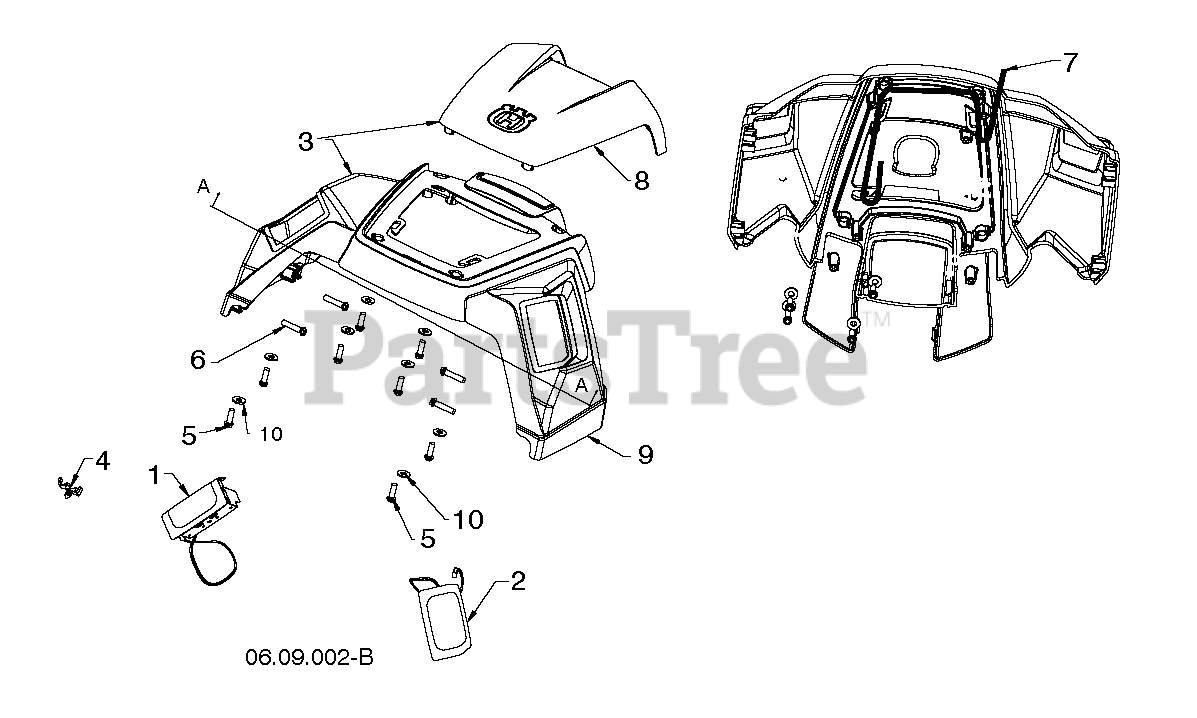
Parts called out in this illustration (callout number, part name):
1	LIGHT.LED.RH.SUBASM 12
2	LIGHT.LED.LH.SUBASM 12
3	CONTROL.SHROUD.SNOW
5	SCREW.HX.13X.750
6	SCREW.HWH.13-16X1.12
7	HARNESS.LED
8	SUBASM.CONTROL.SHROUD
9	COVER.HANDLE.LG.SHROUD
